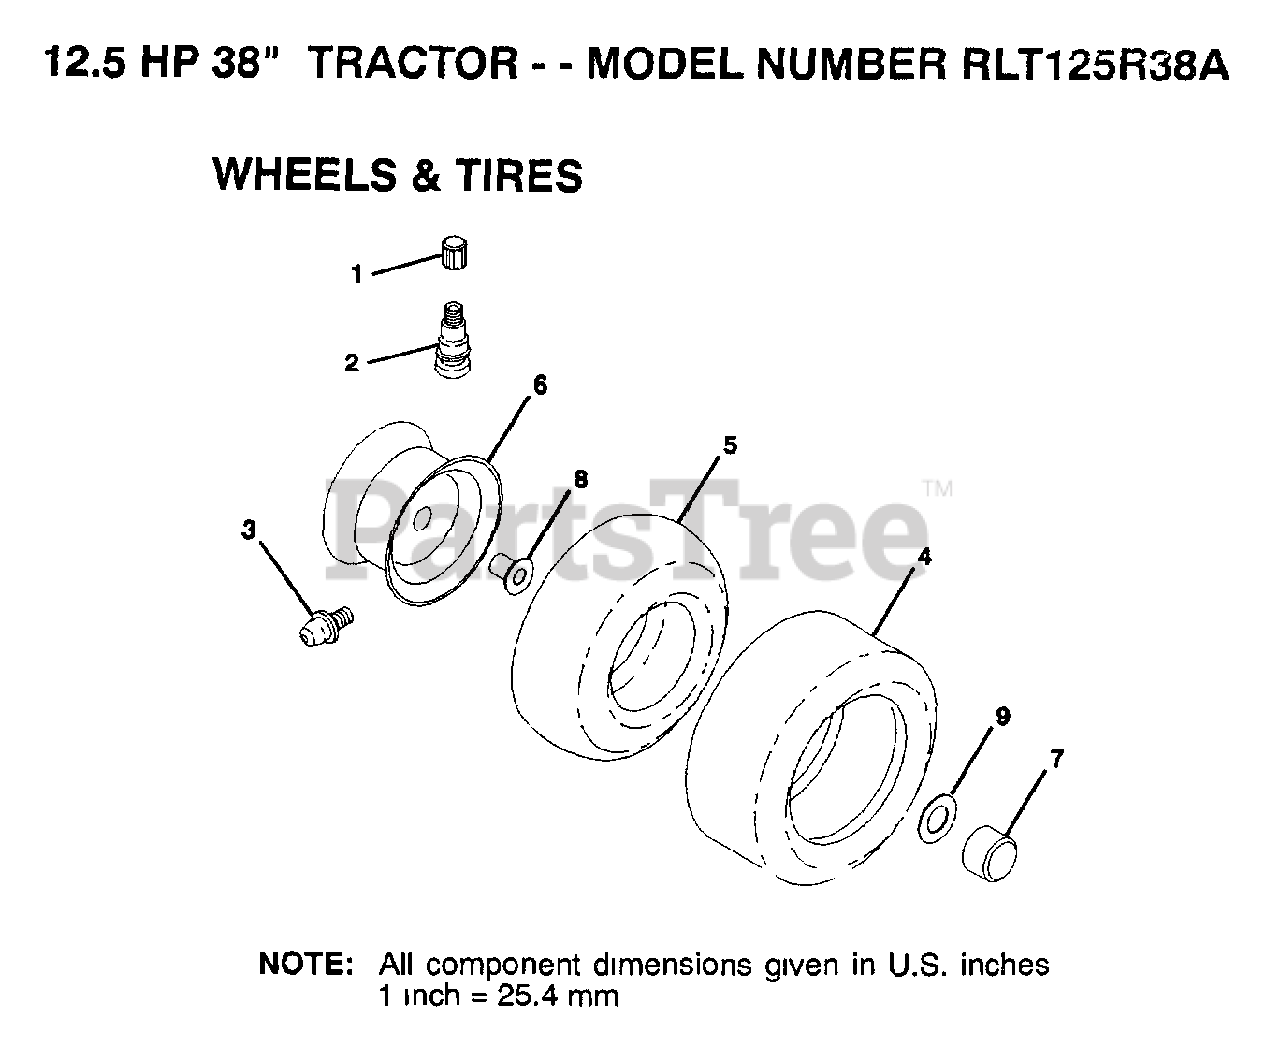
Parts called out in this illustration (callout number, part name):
1	VALVE CAP
2	VALVE STEM LT
3	FITTING LT
5	TUBE.5.3/4.5/6
7	HUB CAP
8	"FLANGE, BEARING"
9	WASHER
